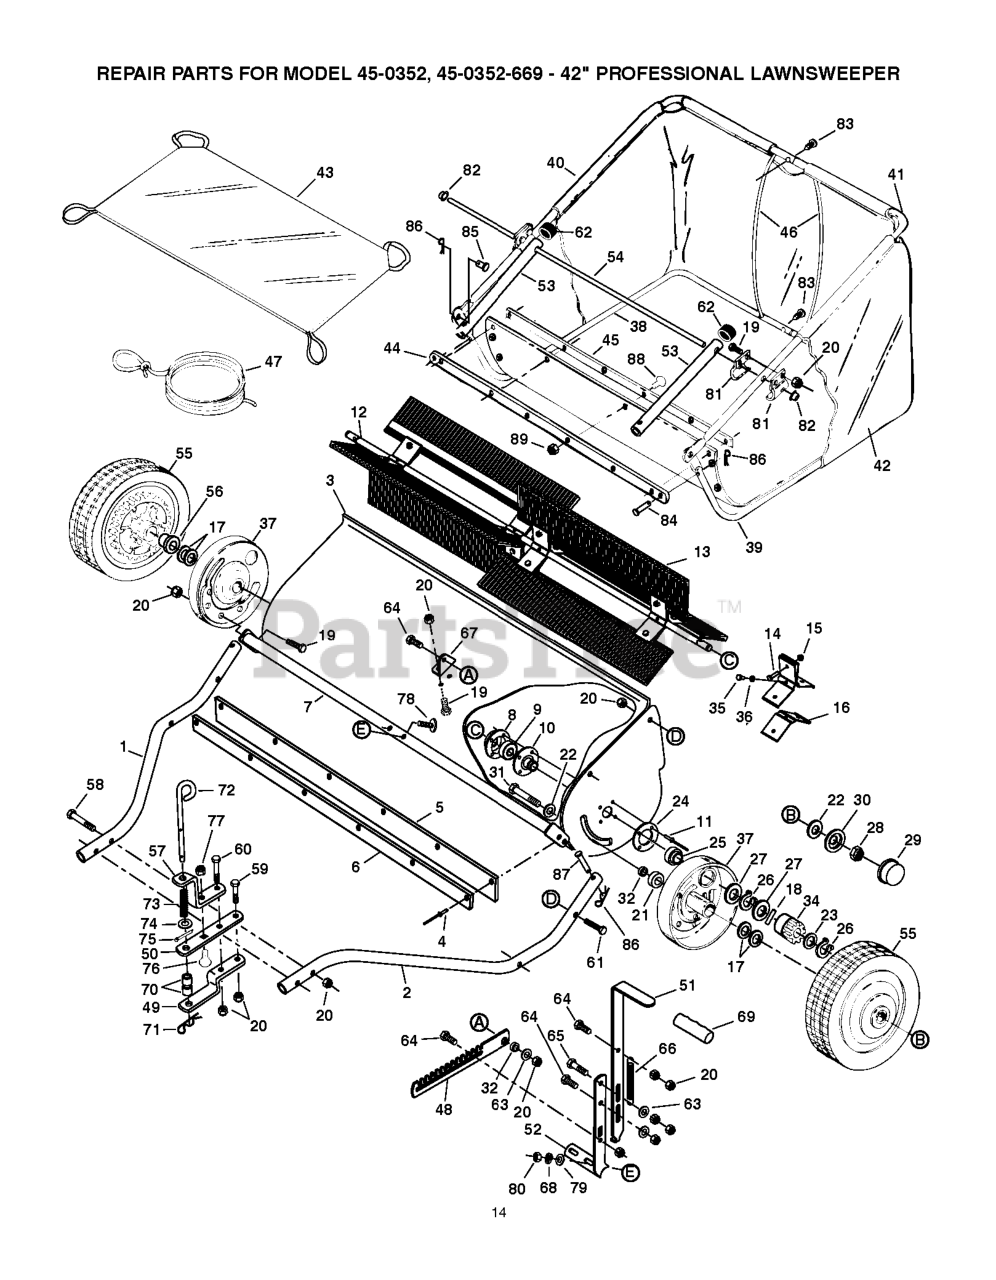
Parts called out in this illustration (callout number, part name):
1	Hitch Tube, R.H.
2	Hitch Tube, L.H.
3	Housing Assembly
5	Skirt, 42"
6	Retainer, Skirt
7	Height Adjustment Tube Ass'y.
8	Retainer, Dust Cover
9	BEARING. BALL
10	Brush Bushing Ass'y.
12	Brush Shaft
13	Brush, 42"
14	Hex Bolt 1/4-20 x 1.0" Lg.
15	Hex Nut, Nylock 1/4-20 Thread
16	Brush Retainer
17	Washer, Flat .78" x 1.25" x .06"
18	Dowel Pin (Drive)
19	Bolt, Hex 5/16-18 x 3/4" Lg.
20	Hex Nut, Nylock 5/16-18 Thread
21	Spacer, .41" x 1.125" x .50"
22	Washer, Flat 1-1/2" x .375" x .062"
23	Washer, Flat .596 x .859 x .025
24	Washer, Special
25	Spacer, .78" x 1.25" x .50"
26	Retaining Ring - .594" I.D.
27	Fl.-Washer (Shim) .596 x 1.125 x .025
28	Nut, Hex Lock 3/8-24 Thread
29	Hub Cap
30	Washer, Hub Cap
31	Bolt, Hex 3/8-24 x 3-1/4" Lg.
32	Spacer 13/32 x 5/8 x 3/16
34	Gear, Pinion L.H.
35	Hex Bolt 1/4" x 5/8" Lg.
36	WASHER, 1/4" SPRING LOCK
37	Dust Cover Assembly
38	Tube, Lower Hopper Frame R.H.
39	Tube, Lower Hopper Frame L.H.
40	Tube, Upper Hopper Frame R.H.
41	Tube, Upper Hopper Frame L.H.
42	Hopper Bag
43	Wind Screen
44	Strap, Bag Frame
45	Retainer, Bag
46	Hopper Support Rod 34" Lg.
47	Hopper Rope
48	Strap, Height Adjustment
49	Bracket, Hitch
50	Bracket, Hitch (Straight)
51	Handle, Upper Height Adjustment
52	Handle, Lower Height Adjustment
53	Tube, Bag Arm
54	Rod, Hopper Bag Pivot
55	Wheel & Tire Ass'y.
56	Wheel Bearing
57	Bracket, Hitch Pin
58	Bolt, Hex 5/16-18 x 3" Lg.
59	Bolt, Hex 5/16-18 x 2-1/4" Lg.
60	Bolt, Hex 5/16-18 x 2-1/2"
61	Hex Bolt, 5/16-18 x 1-3/4" (Grade 5)
62	Cap, Vinyl
63	Washer, Flat 5/16" Std. Wrt.
64	Hex Bolt, 5/16-18 x 1" (Grade 5)
65	Hex Bolt, 5/16-18 x 1-1/4" Lg.
66	Spring, Extension
67	Angle Bracket
68	Spring Lock Washer 5/16"
69	Grip, Height Adjust
70	Hitch Adjustment Tubes
71	Hairpin Cotter, 3/32" x 2-5/16"
72	Pin, Hitch
73	Spring, Hitch Pin
74	Washer, 7/16" Flat
75	Pin, Cotter 1/8" x 3/4" Lg
76	Bolt, Carriage 3/8-16 x 1" (Grade 5)
77	Hex Nut, Nylock 3/8-16 Thread
78	Bolt, Cvd. Hd. 5/16-18 x 1-5/8" Lg.
79	Washer, Bowed 1" x .32" x .06"
80	Nut, Hex 5/16-18 Thread
81	Hopper Mounting Clamps
82	Palnut, 3/8"
83	Plug, 1/4"
84	Pin, Clevis 1/4" x 1-1/8" (Special)
85	Pin, Clevis 3/8" x 1/2" (Special)
86	Hairpin Cotter, 3/32" x 1.8"
87	Pin, Clevis 1/4" x 1-1/2" Lg.
88	Truss Hd. Slotted Scr. #10-32 x 5/8" Lg.
89	Nylock Nut, #10-32
